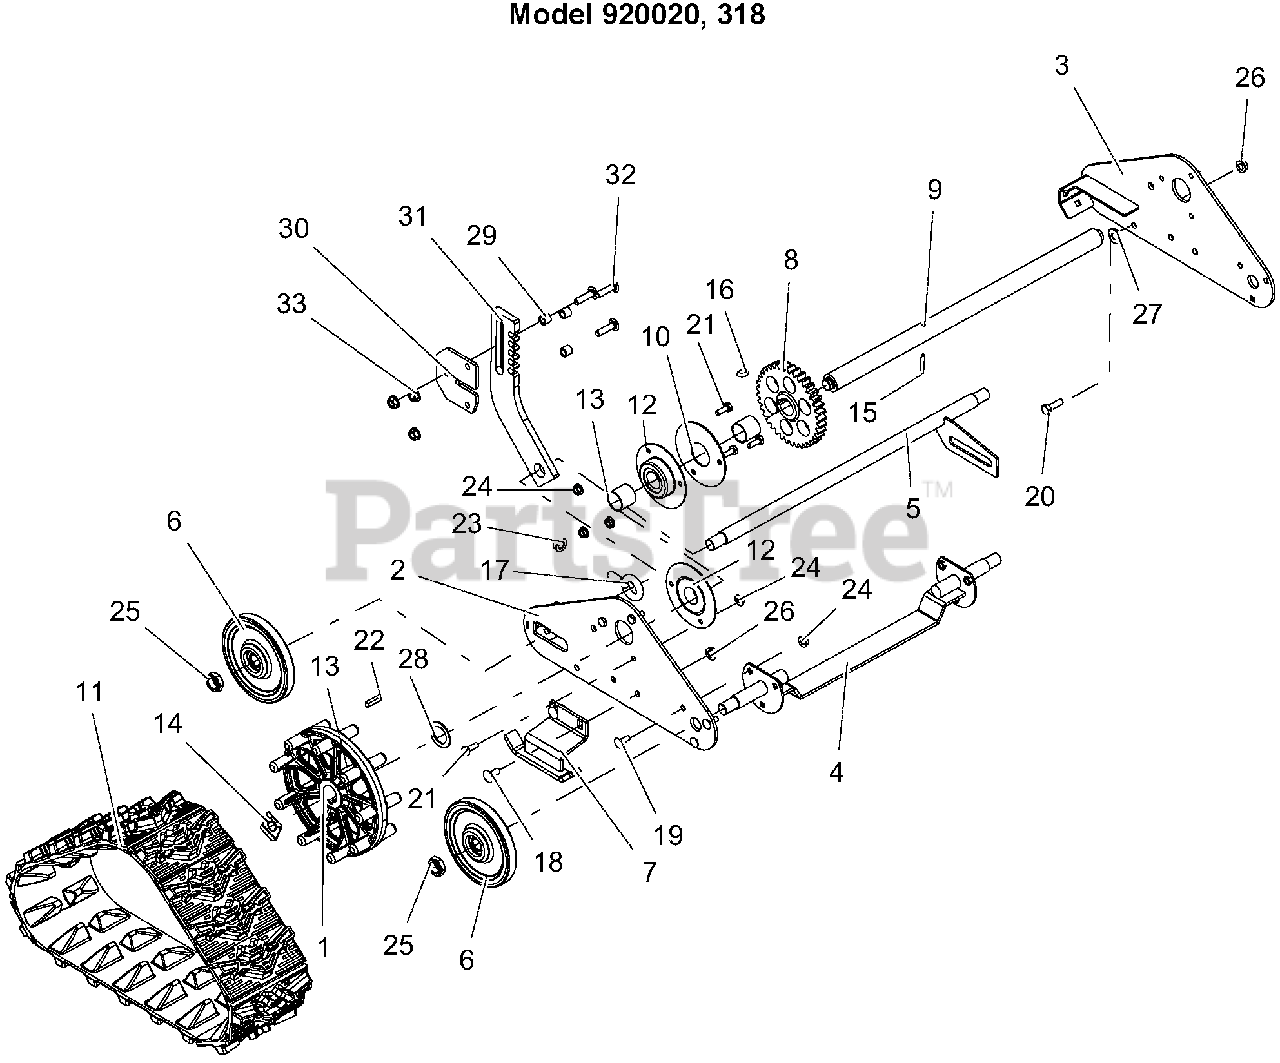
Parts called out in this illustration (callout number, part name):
1	WHEEL, MACHINED DRIVE
2	SIDE PLATE, RH COMPACT BLACK
3	SIDE PLATE, LH-COMPACT TRACK B
4	AXLE, FRONT-COMPACT TRACK
5	AXLE, REAR - DELUXE TRACK
6	WHEEL, BOGIE - SINGLE BEARING
7	RUNNER, GUIDE-CMPT TRACK BLACK
8	GEAR, SPUR
9	AXLE, TRACK-DELUXE
10	PLATE, BEARING SPACER
11	TRACK, RUBBER COMPACT
12	BRG-FLG 1.003/1.000 3 BOLT
13	BSHG-SLV, 1.012X1.125X1.00
14	CLIP, SNAP .625 DIA
15	PIN-ROLL .188X1.25
16	KEY-WDRF .25X.750X.313 SAE91
17	BLT-EYE .375-16X.880 YWZC
18	@BLT-RDHDSQNK .31-18X.75 G5YZ
19	@BLT-RDHDSQNK .25-20X.75 G5YZ
20	@BLT-HEX .31-18X1.00 GR5 YWZC
21	@BLT-HEX .25-20X.75 GR5 YWZC
22	KEY-RECT .25X.188X1.00
23	NUT-LK-CTR-FLG .38-16 YWZC
24	@NUT-LK-CTR-FLG .25-20 YWZC
25	@NUT-LK-NYL .625-18 YWZC
26	@NUT-LK-TOP-FLG .31-18 YWZC
27	BSHG-FLG .325X.499X.3X.875
28	WSHR-FL-STL 1.010X1.505X.062YZ
29	SPACER .50 X .32 X .42
30	PLATE, HEIGHT ADJUSTER
31	STOP, HEIGHT ADJUSTER-CPT BLAC
32	@BLT-RHDSHSQNK.31-18X1.25 G5YZ
33	@NUT-LK-TOP-FLG .31-18 YWZC
